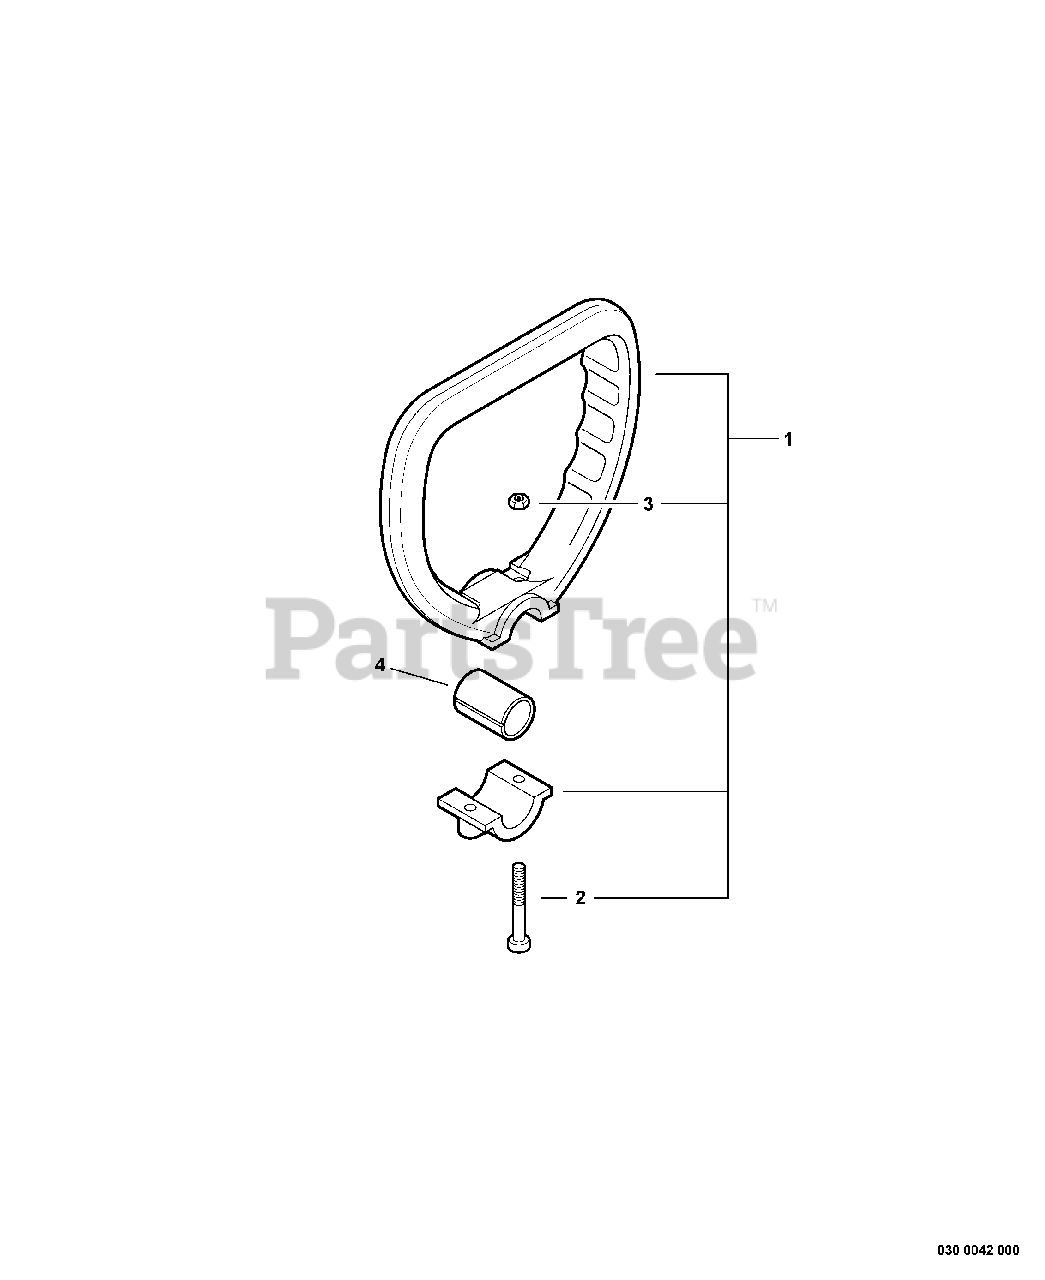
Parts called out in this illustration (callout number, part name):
1	HANDLE ASSY - SUPPORT
2	BOLT, TORX 5×35
3	NUT M5
